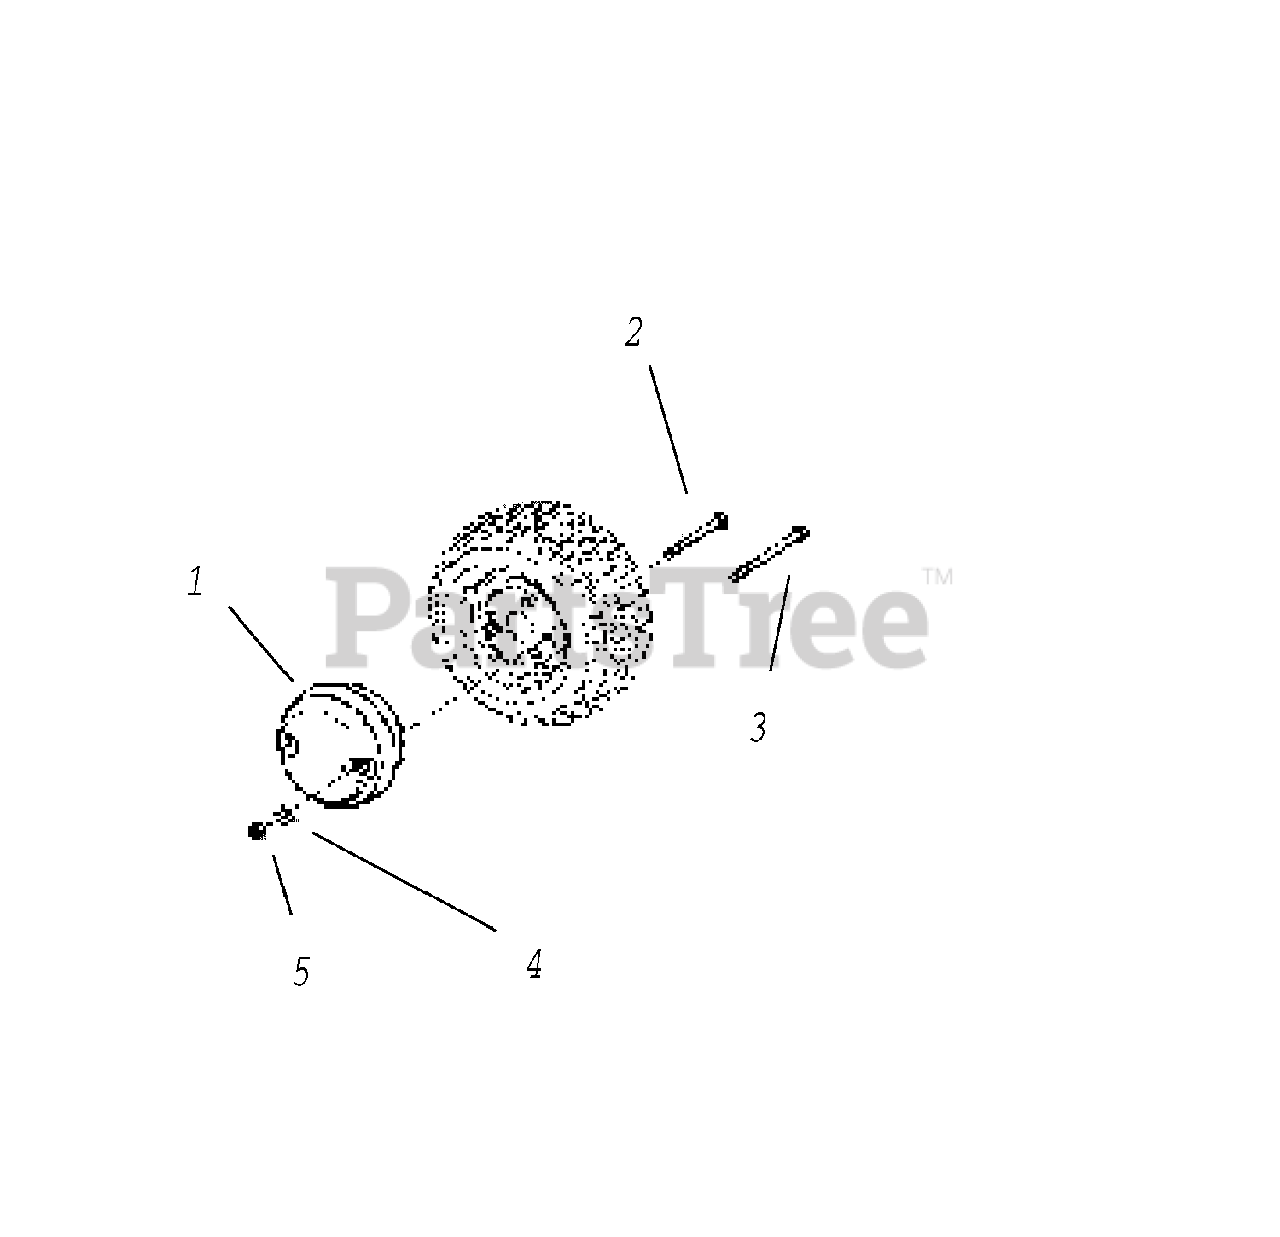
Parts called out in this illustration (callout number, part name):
1	WHEEL WEIGHT
2	BOLT, 3/8" x 3-3/4" Lg. (USE WITH SERF)
3	BOLT, 3/8" x 5-1/2" Lg. (USE WITH BROADMOOR AND YEOMAN)
4	LOCKWASHER, 3/8"
5	NUT, 3/8"
